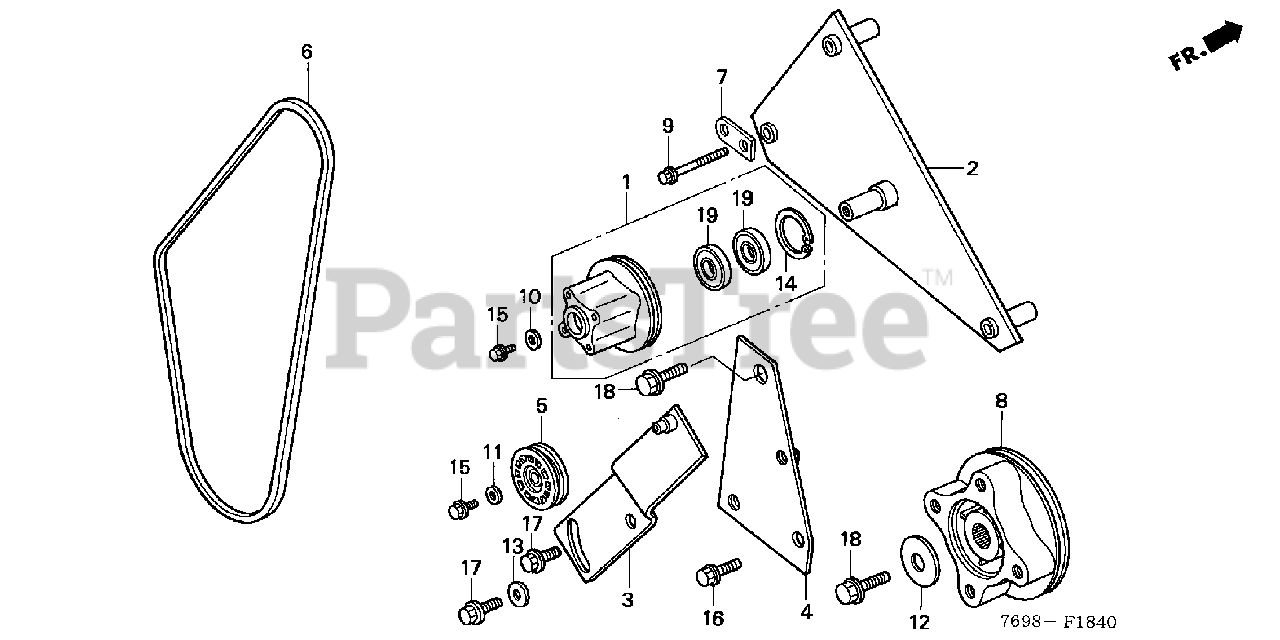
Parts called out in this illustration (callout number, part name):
1	PULLEY ASSY., COOLING FAN
2	BRACKET, COOLING FAN
3	ARM, TENSION
4	PLATE, TENSIONER ARM
5	PULLEY, TENSIONER (65MM)
6	BELT, ALTERNATOR (BANDO)
7	BRACKET, WIRE HARNESS CLIP
8	JOINT, PROPELLER SHAFT
9	BOLT, FLANGE (6X50)
10	WASHER, GEARSHIFT DRUM SIDE
11	WASHER (6MM)
12	WASHER (10.5X40X4)
13	WASHER, PLAIN (10MM)
14	CIRCLIP (INNER) (32MM)
15	BOLT, FLANGE (6X12)
16	BOLT, FLANGE (8X20)
17	BOLT, FLANGE (10X20)
18	BOLT, FLANGE (10X25)
19	BEARING, RADIAL BALL (6201UU)
